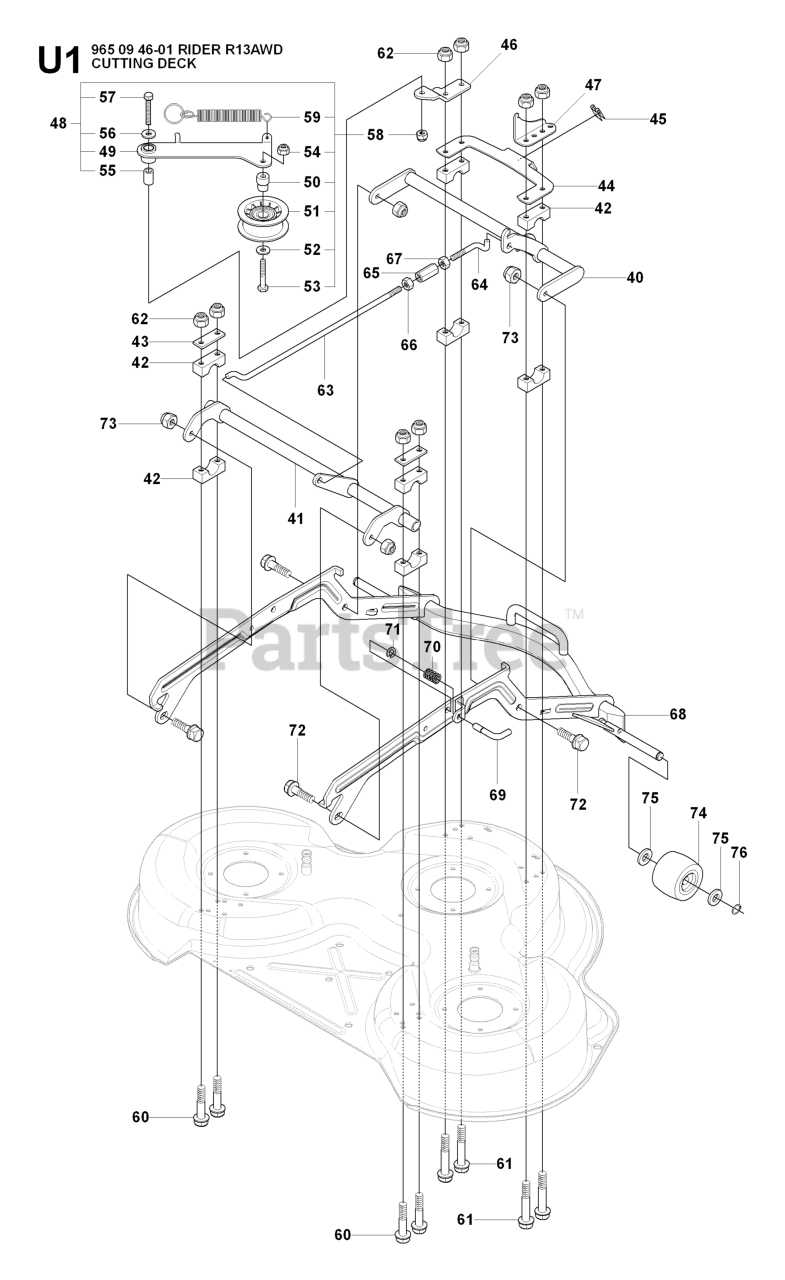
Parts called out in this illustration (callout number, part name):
51	PULLEY
54	LOCKNUT M8
57	SCREW
58	LOCKNUT M8
62	LOCKNUT M8
67	NUT
73	LOCKNUT M8
74	DECK ROLLER, FRONT
76	RETAINING RING SGA 15
